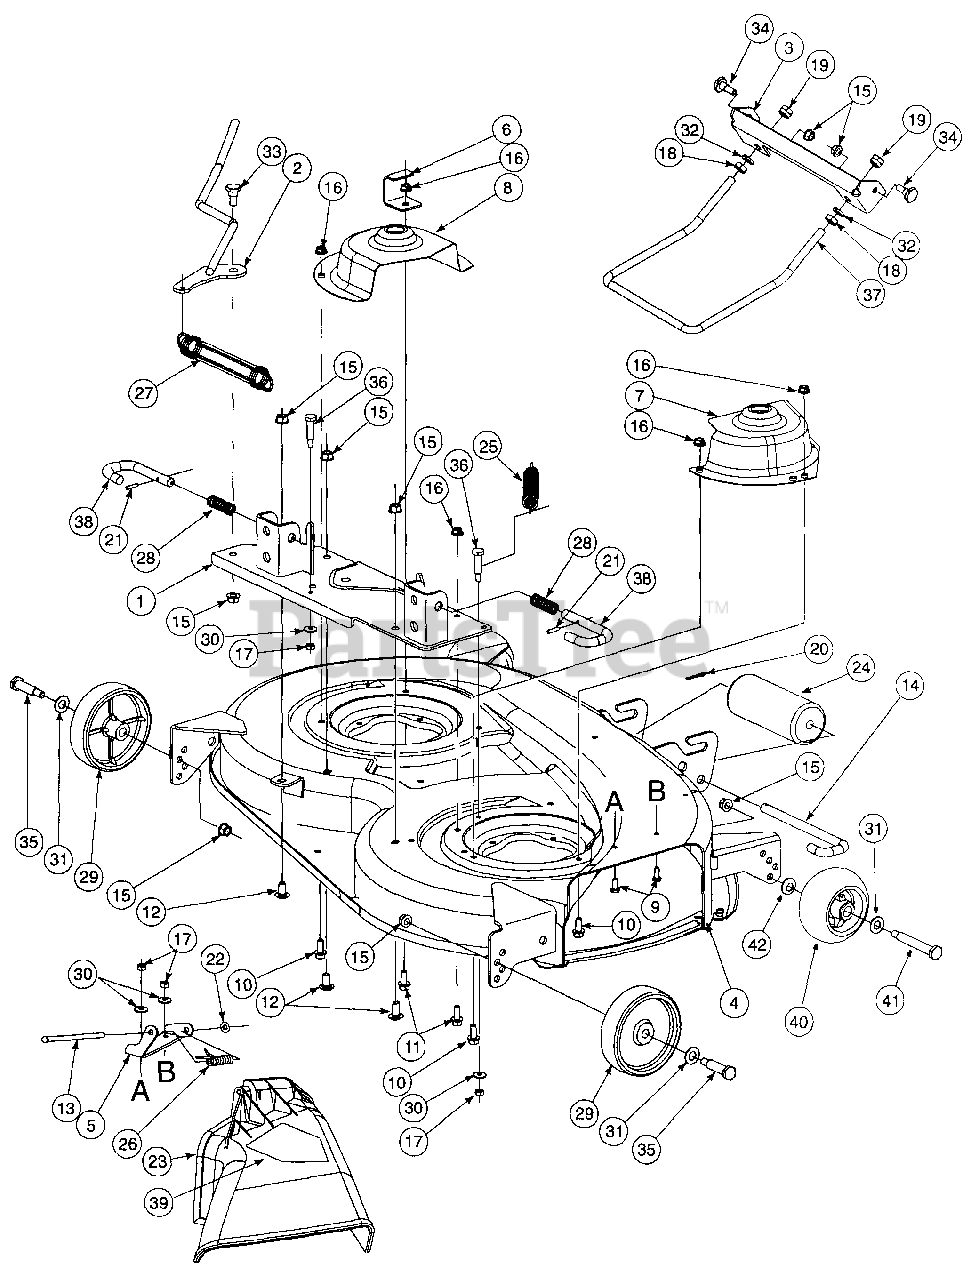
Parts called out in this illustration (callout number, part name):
1	Plate Assembly, Mounting
3	Bracket, Front Lift
4	Deck Assy, 42" w/out Front Wheels
4	Deck Assy, 42" w/Front Wheels
4	Graphic, Danger Top/RH Deck
4	Graphic, Tension Lever
4	Graphic, Safety Top/LH Deck
4	Graphic, Assembly Chute
5	Bracket, Hinge Mounting
6	Bracket, Handle Stop
7	Shield, RH Pulley
8	Shield, LH Pulley
9	Screw, Hex Cap, 1/4-20 x .62 GR5
10	Screw, Hx Wsh Hd Tapp, 5/16-18 x.75
11	Screw, Hex Cap, 5/16-18 x .75 GR5
12	Bolt, Carriage, 3/8-16 x .75
13	Pin, Hinge, .25 Dia x 6.75 Lg
14	Pin, Roller, 1/2 Dia x 7.31 Lg
15	Nut, Hex Flange Lock, 3/8-16
16	Nut, Hex Flange Lock, 5/16-18 GR5
17	Nut, Hex, 1/4-20
18	Nut, Hex Jam, 1/2-13 GR5
19	Nut, Hex Insert Lock, 1/2-13
20	Pin, Cotter, 3/32 x 1.25
21	Pin, Spirol Spring, 3/16 x .75
22	Cap, Speed Nut
23	Deflector Assy,
25	Spring, Extension, .88 OD x 6.12
26	Spring, Torsion
27	Spring, Extension, 1.25 OD x 8.15
28	Spring, Compression
29	Wheel, Deck, 5 in. Dia
30	Washer, Bell, .265 x .75 x .062
31	Washer, Flat, .510 x 1.0 x .060
32	Washer, Lock, 1/2
33	Bolt, Shoulder, .498 Dia x .340 Lg
34	Bolt, Shoulder, .50 Dia x .434 Lg
35	Bolt, Shoulder, .498 Dia x 1.64 Lg
36	Bolt, Shoulder, .375 Dia x 1.16 Lg
37	Rod, Front Lift
38	Pin, Mower Support
39	Graphic, Danger
40	Wheel, Deck w/Fitting
40	Lube Fitting
41	Bolt, Shoulder, 1/2 x 2.5
42	Washer, Bell, .401 x .870 x .063
